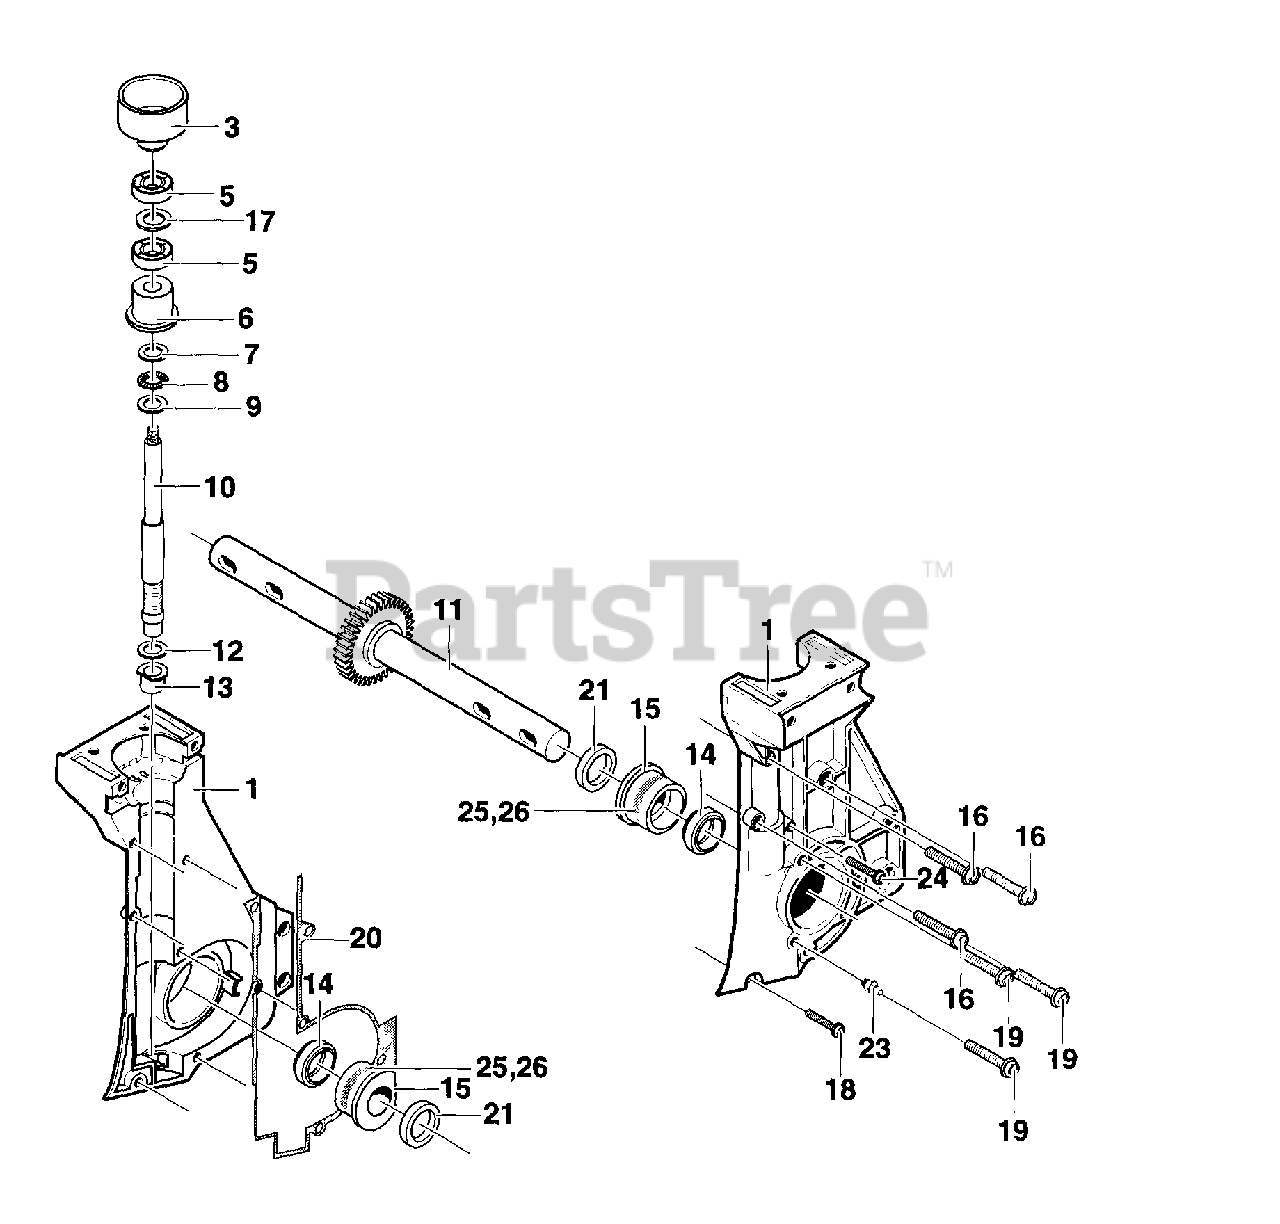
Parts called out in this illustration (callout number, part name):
1	GEARCASE HALF - RIGHT
2	GEARCASE HALF - LEFT
4	SEALANT, GASKET ELIMINATOR
5	SEAL - OIL
6	BRNG, FL .501IDX1.002ODX .63
7	WASHER, THRUST
8	NEEDLE BEARING
9	WASHER, FLAT .50X .94X.120
10	SHAFT, WORM
11	SHAFT/GEAR - LONG
12	WASHER, FLAT .506X .75X.024
13	BRNG, FL .502IDX .752ODX .75
14	SEAL, OIL, .75 X 1.19 X .25
15	BRNG, FL .751IDX1.50 ODX.765
16	SCREW, 1/4-20X1.25 HHWATAP
17	WASHER, FLAT .515X .94X.104
18	SCREW, 10-24X.62 HHWATAP
19	SCREW, 1/4-20X1.75 HHWATAP
20	GASKET,GEARCASE/TILLER/ 02
21	WASHER, FLAT .76 X1.25X.104PL
23	FITTING, GREASE - .69 0.A.L
24	SCREW, 10-24X.38 SLHWATAP
